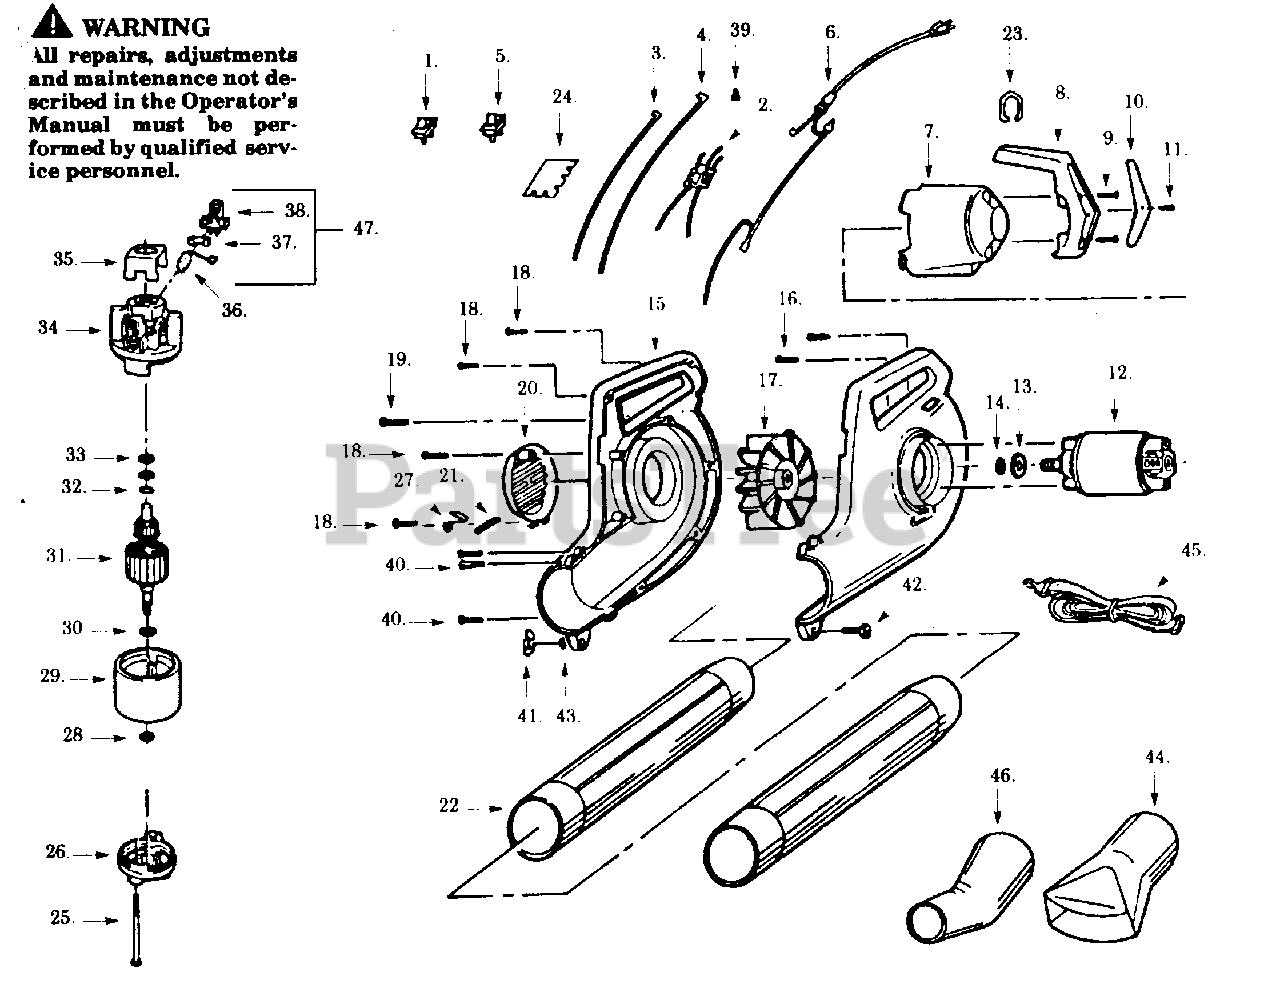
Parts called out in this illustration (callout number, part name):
1	On-Off Switch
2	P.C. Board Ass'y.
3	Lead Wire Ass'y.
4	Lead Wire Ass'y.
5	Speed Switch
6	Power Cord Ass'y.
7	Motor Cover
14	Retainer Ring
15	R.H./L.H. Housing
17	Impeller Ass'y.
20	Inlet Cover
21	Hinge Pin
22	Outlet Tube
24	Mounting Board
26	Endbell Output
29	Field Ass'y.
30	Retainer Ring
31	Armature
32	Retainer Ring
34	Endbell (Brush)
35	Insulator
37	Brush Spring
38	Brush Holder
39	Connector
41	Wing Nut
44	Diffuser Ass'y.
45	Shoulder Strap
46	Curved Nozzle
47	Brush Kit (Incl. 36,37,38)
